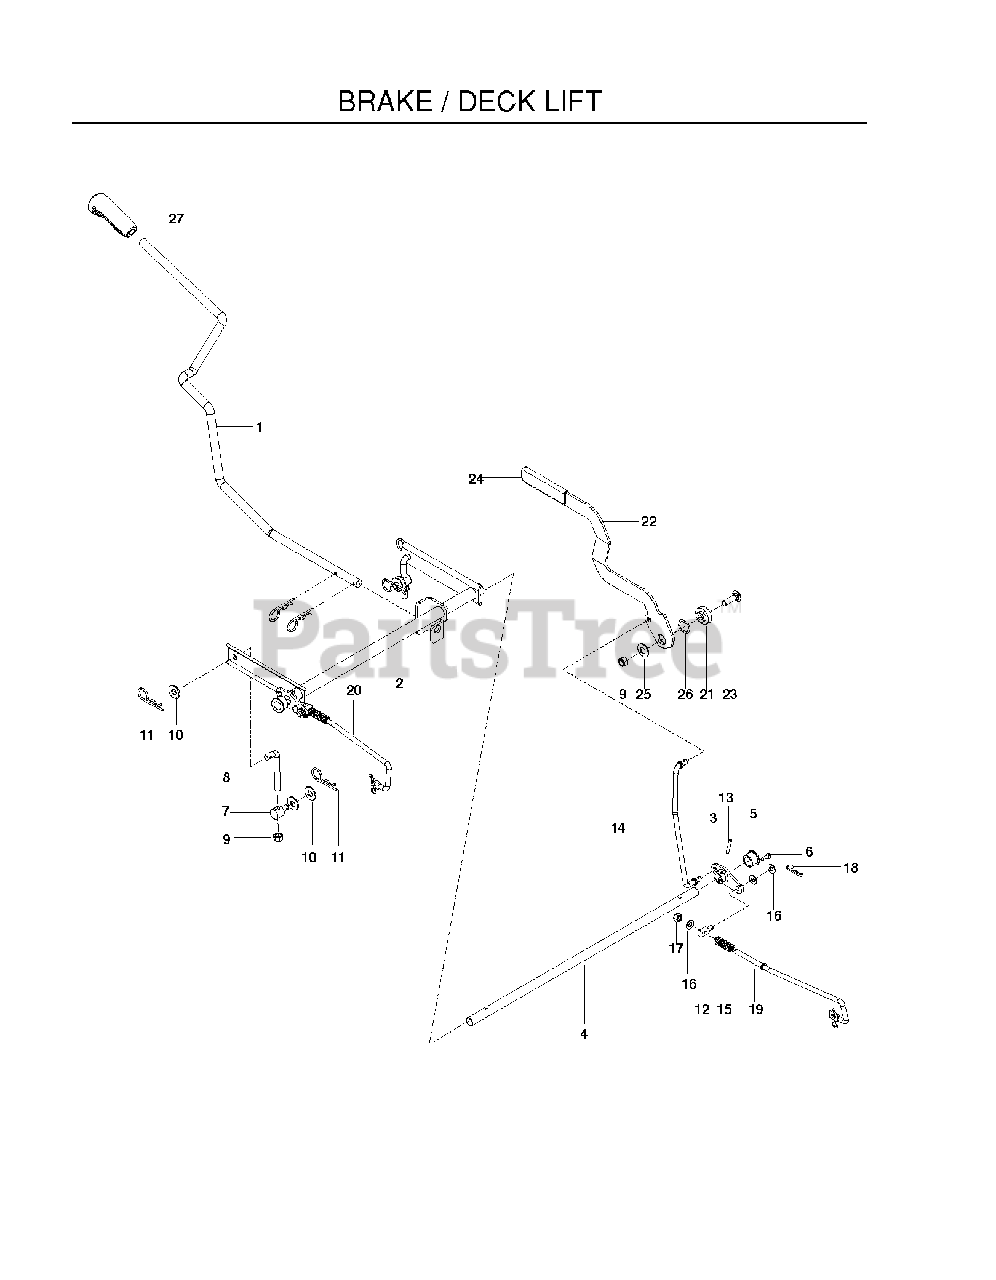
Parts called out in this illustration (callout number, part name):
1	ARM, LIFT HANDLE, BLK
2	SHAFT, LIFT WLDMT, BLACK
3	BELLCRANK, BRAKE
4	ROD, BRAKE
5	PLASTIC BUSHING
6	SCREW #10 X 1/2 SELF TAPPING
8	L ROD 3-1/8"
9	NUT 3/8-16 NYLOC
10	WASHER 3/8 FLAT
11	HAIRPIN #4
12	BRAKE SWIVEL
13	ROLL PIN 3/16 X 1-1/4 ZD
14	LINKAGE, BRAKE, UPPER
16	FLAT WASHER 5/16 SAE
17	NUT 5/16 NYLOC
18	HAIRPIN #2
19	LINKAGE, EZT BRAKE RT
20	LINKAGE, EZT BRAKE LT
21	BRAKE ARM PIVOT
22	HANDLE, BRAKE, BLK
23	RHSNB 3/8-16 X 1-1/4
24	GRIP BRAKE HANDLE
25	WASHER, 7/16 DISC SPRING
26	WASHER, .825 X 1.087, WAVE
27	GRIP.LEVER.5625.ID
